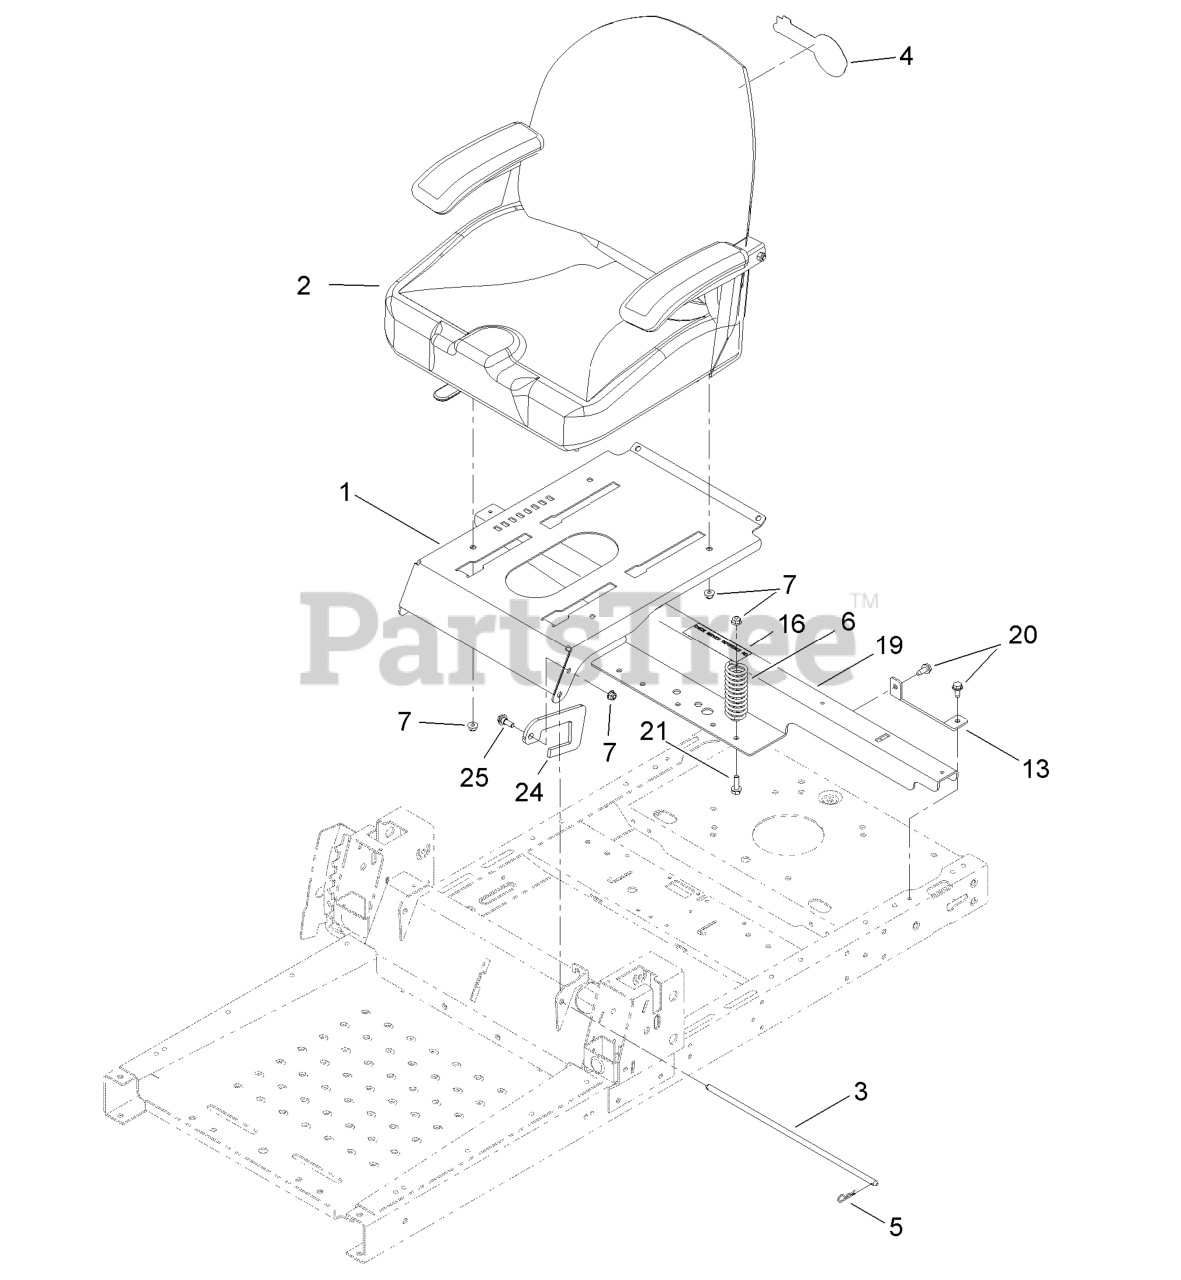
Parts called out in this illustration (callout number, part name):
2	SEAT ASM
3	ROD-STOP
5	PIN-COTTER
6	SPRING-COMPRESSION
7	NUT-HF, NI
13	SUPPORT-TANK, REAR
16	DECAL-SERVICE, CE
19	SUPPORT-POD
20	Screw-HWH 5/16-18 X 3/4 Tf
21	SCREW-HHF
24	STOP-SEAT
25	SCREW-SHOULDER
